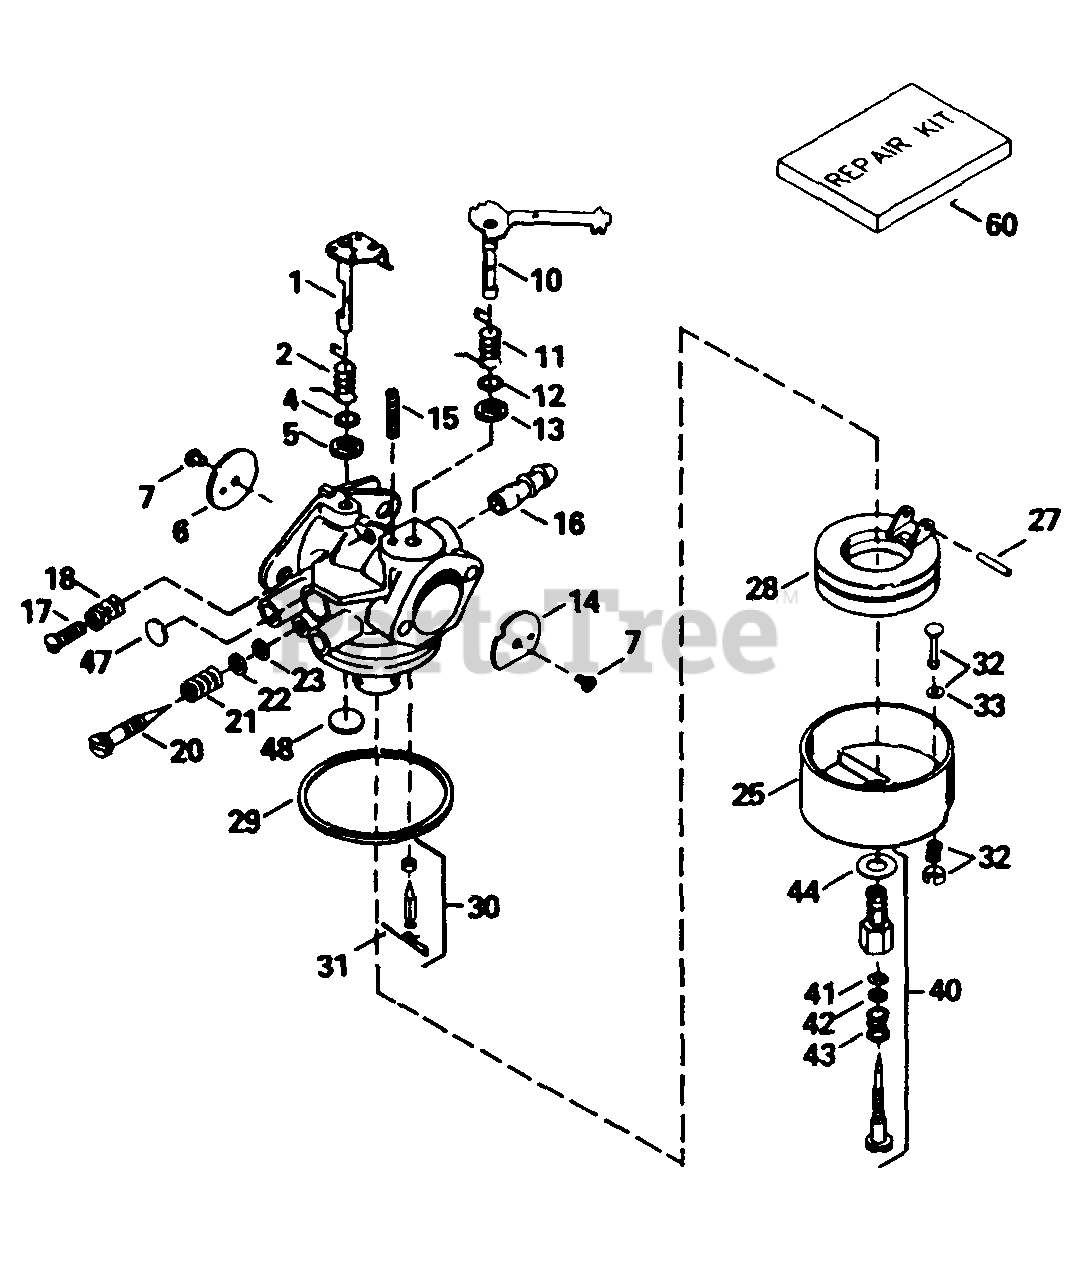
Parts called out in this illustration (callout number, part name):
1	Throttle Shaft & Lever Ass'y.
2	Throttle Return Spring
6	Throttle Shutter
7	Throttle & Choke Shutter Screw
10	Choke Shaft & Lever Ass'y.
14	Choke Shutter
15	Choke Positioning Spring
16	Fuel Fitting
17	Idle Speed Screw
18	Tension Spring
20	Idle Mixture Screw
21	Idle Tension Spring
22	Washer, Idle Screw
23	O-Ring, Idle Screw
25	Float Bowl Ass'y.
27	Shaft, Float
28	Float
29	O-Ring, Float Bowl to Body
30	Inlet Needle, Seat & Clip
31	Spring Clip
32	Bowl Drain Ass'y.
33	Drain Plunger Gasket
40	Main Adj. Screw Ass'y.
41	O-Ring, High Speed Mixture Screw
42	Washer, High Speed Mixture Screw
43	Tension Spring, High Speed Mixture Screw
44	Bowl Nut Washer
47	Welch Plug, Idle Mixture Well
48	Welch Plug, Atmospheric Vent
60	Repair Kit
